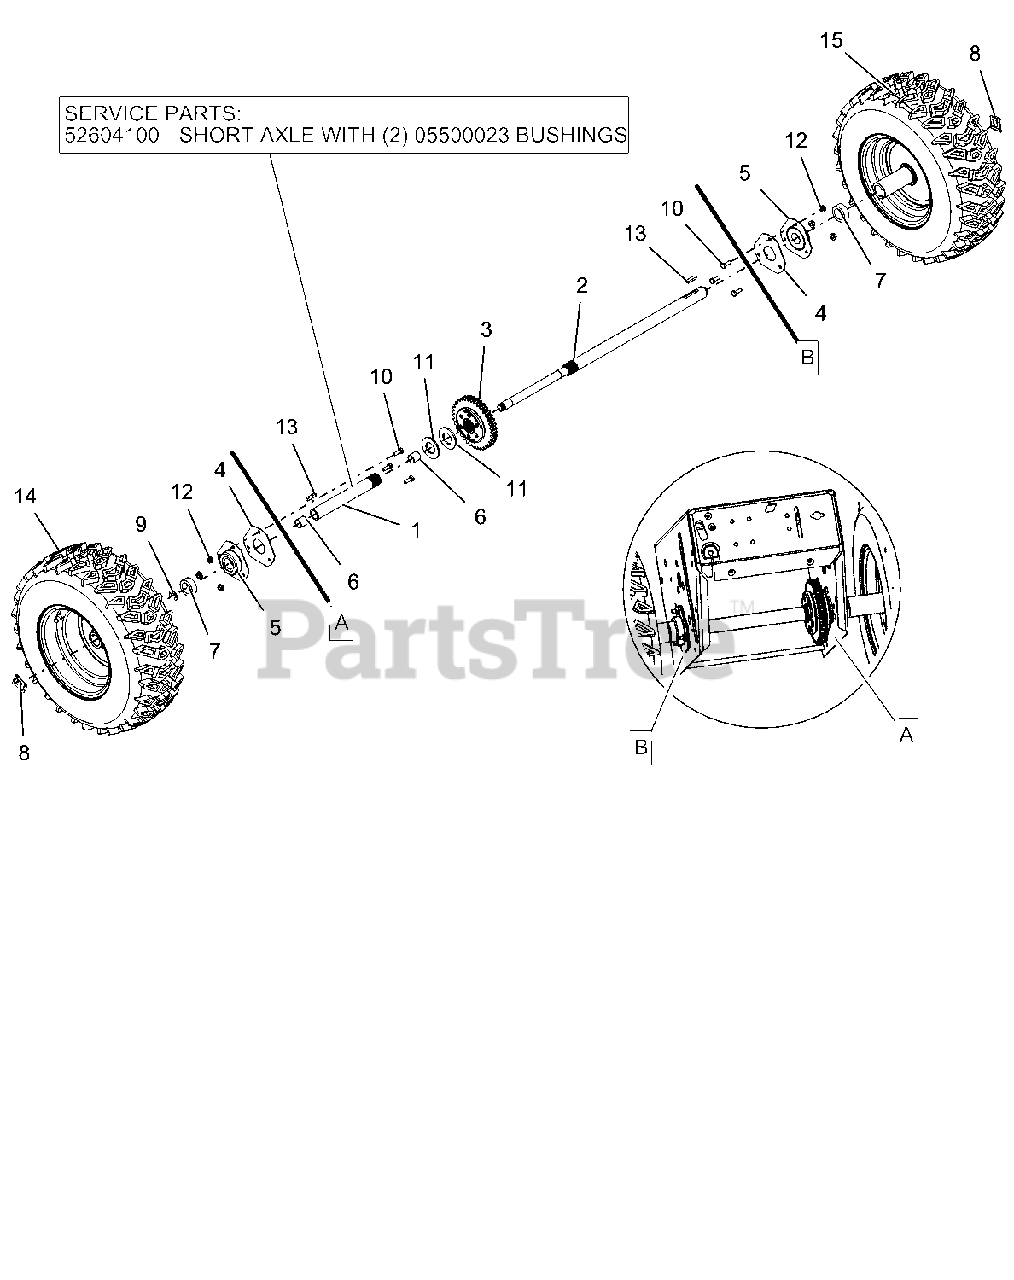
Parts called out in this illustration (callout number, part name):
1	BSHG-SLV .706X.764X.75 BRZ
1	AXLE, SHORT-PRO AUTO DIFF
1	AXLE, SHORT-AUTO W/BUSHINGS
2	AXLE, LONG-PRO AUTO DIFF
3	DIFFERENTIAL, AUTOMATIC
4	PLATE, BEARING SPACER
5	BRG-FLG 1.003/1.000 3 BOLT
6	BSHG-SLV .706X.764X.75 BRZ
7	SPACER, PRO AXLE BEARING
8	CLIP, SNAP .625 DIA
9	RG-RTNG-EXT .625X.042
10	@BLT-HEX .25-20X.75 GR5 YWZC
11	WSHR-FL-STL- 1.062X2.0X.134 YZ
12	@NUT-LK-CTR-FLG .25-20 YWZC
13	KEY-RECT .25X.188X1.00
14	TIRE/WHEEL,RH 16X6.5-8 DIFF T2
15	TIRE/WHEEL,LH 16X6.5-8 DIFF T2
